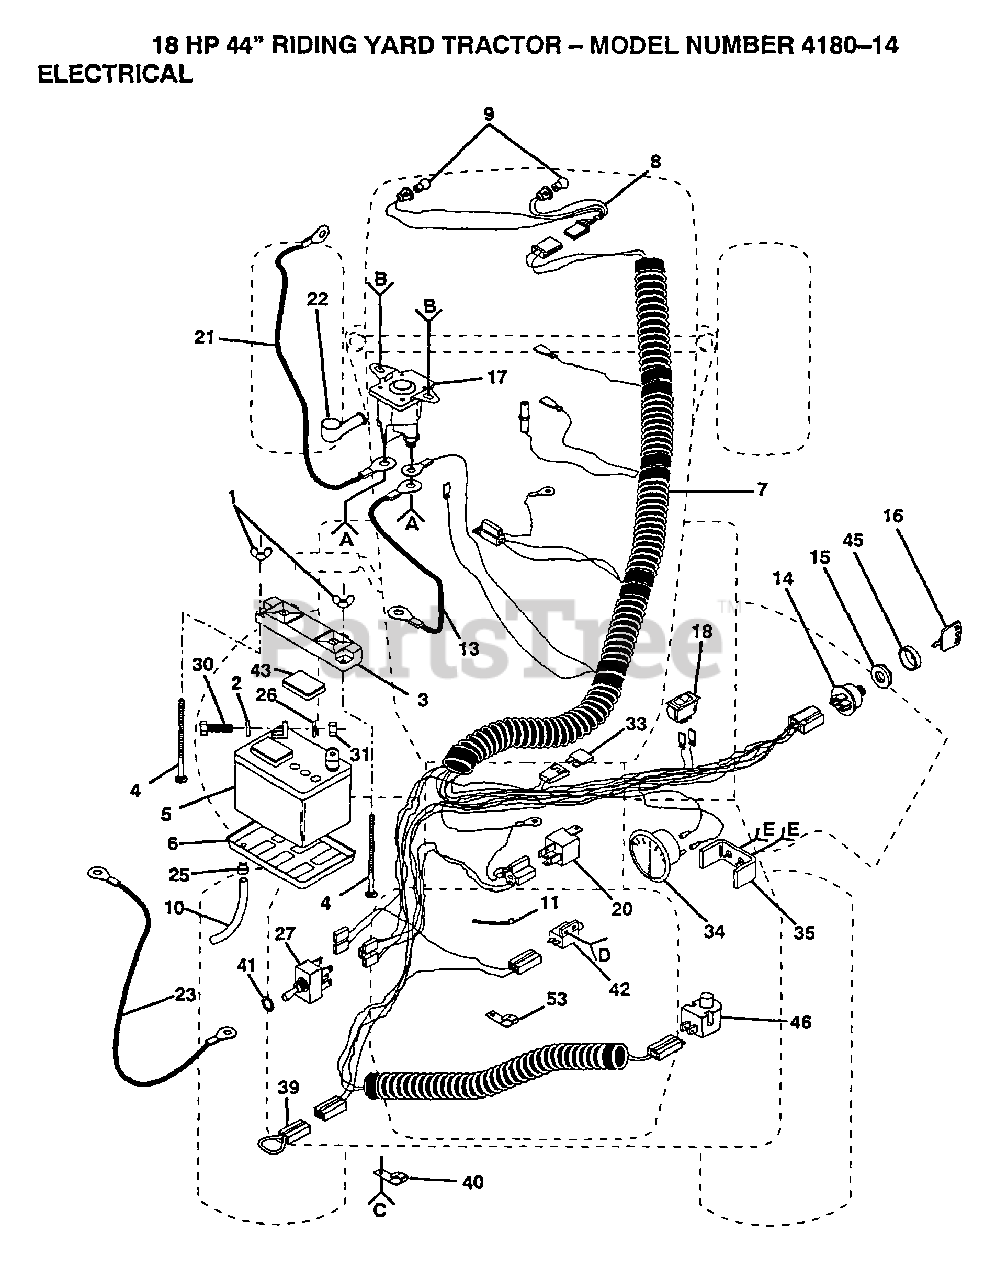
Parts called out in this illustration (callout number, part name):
2	WASHER
4	BOLT
6	"TRAY T, BATTERY"
7	HARNESS
11	WIRE TIE
13	CABLE-BATTERY T
16	KEY
18	SWITCH LT
21	"CABLE T, BATTERY"
23	CABLE T
25	HOSE CLAMP T
26	LOCKWASHER
30	BOLT LT
33	FUSE HYT
34	AMMETER T
40	CLIPT
41	HEX NUT T
42	SWITCH-INTER. GT
43	"CAP,BATTERY "
46	SWITCH SEAT
